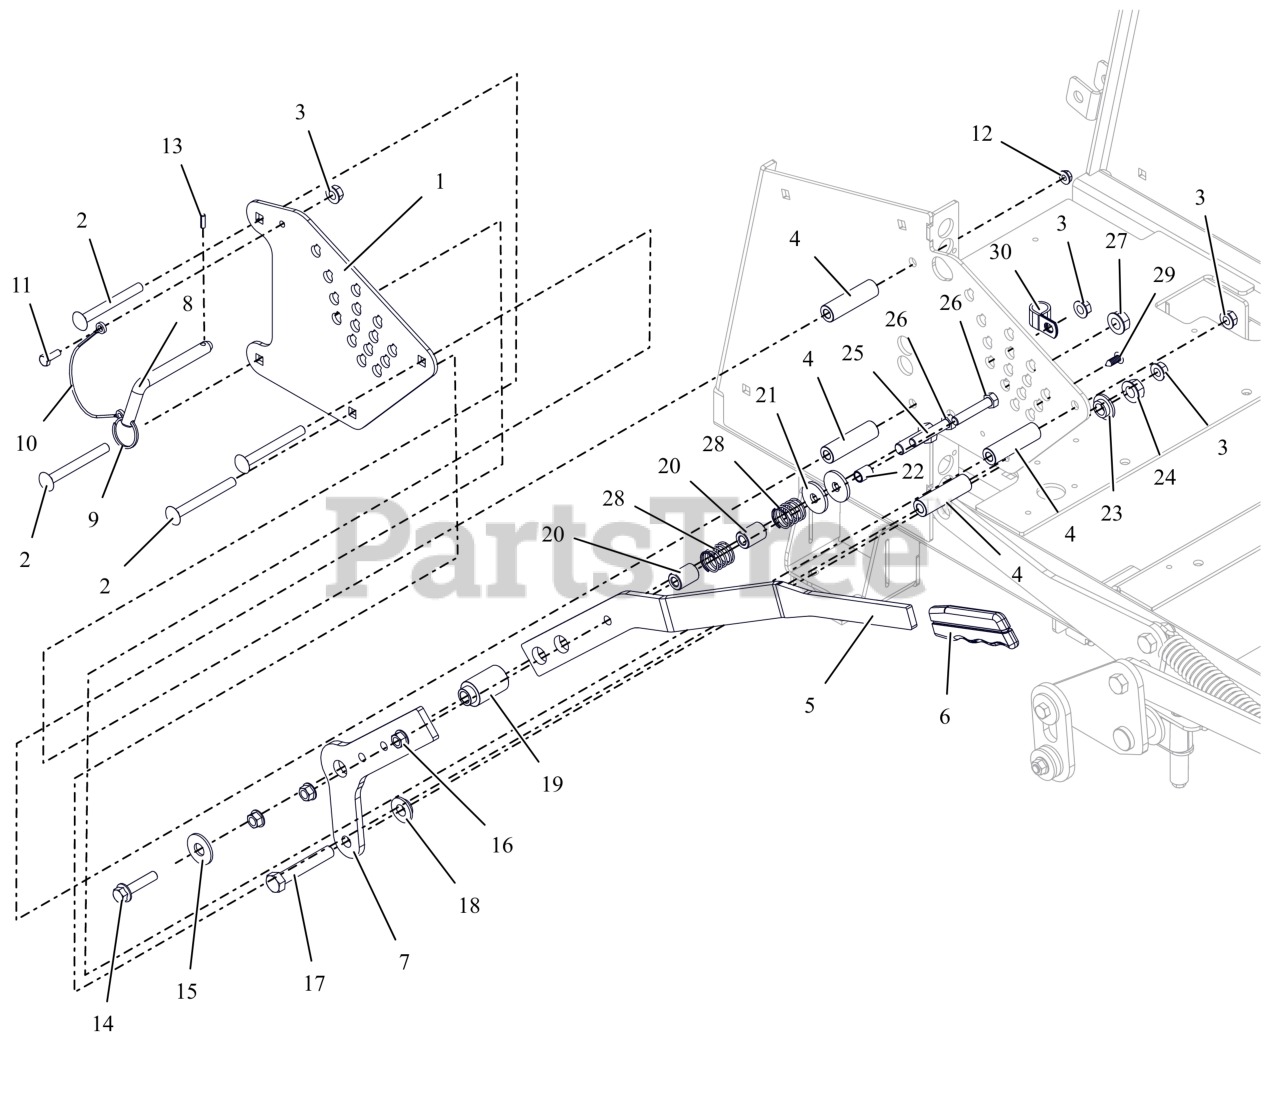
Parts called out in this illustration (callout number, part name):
1	PLATE- HOC PIN LOCATOR (RED)
2	BLT,RHSSN .38-16X3.50 G5 ZCC
3	NUT-LK-CTR-FLG .375-16 GF ZCC
4	SPCR- .390 X .750 X 2.646
5	HANDLE- DECK LIFT UPPER(BLACK)
6	GRIP, PARKING
7	PLATE- HANDLE BASE (BLACK)
8	PIN- HOC SELECTOR
9	RING, WIRE - .080 X 1.25
10	CABLE, 12.0 LANYARD, NYLON
11	BLT, HEX .25-20X.75 G5 ZCC
12	NUT-LK-CTR-FLG .25-20 ZC120
13	PIN-ROLL .188X.63
14	BLT,HEX-FLG .38-16X1.75 G5 ZCC
15	WSHR,FLT .563X1.375X.109 ZCC
16	NUT-LK-CTR-FLG .375-16 GF ZCC
17	BLT, HEX .50-13X3.00 G5 ZCC
18	BSHG-FLG .515X.750X.310X1.120
19	BSHG- SLV .515 X 1.125 X 2.013
20	SPCR- .390 X .750 X 1.063
21	WSHR,FLT .406X1.375X.135 ZCC
22	SPCR, SLV .385X.500X.652
23	BSHG-FLG .515X.750X.310X1.120
24	NUT-LK-CTR-FLG .500-13 GG ZCC
25	BLT,HEX .50-13X1.50 G5 ZCC
26	BLT,HEX .38-16X2.00 G5 ZCC
27	NUT-LK-CTR-FLG .500-13 GG ZCC
28	SPRING- COMPRESSION
29	RIVET, .25 NYLON PANEL
30	CLAMP, CUSHIONED STEEL .75
